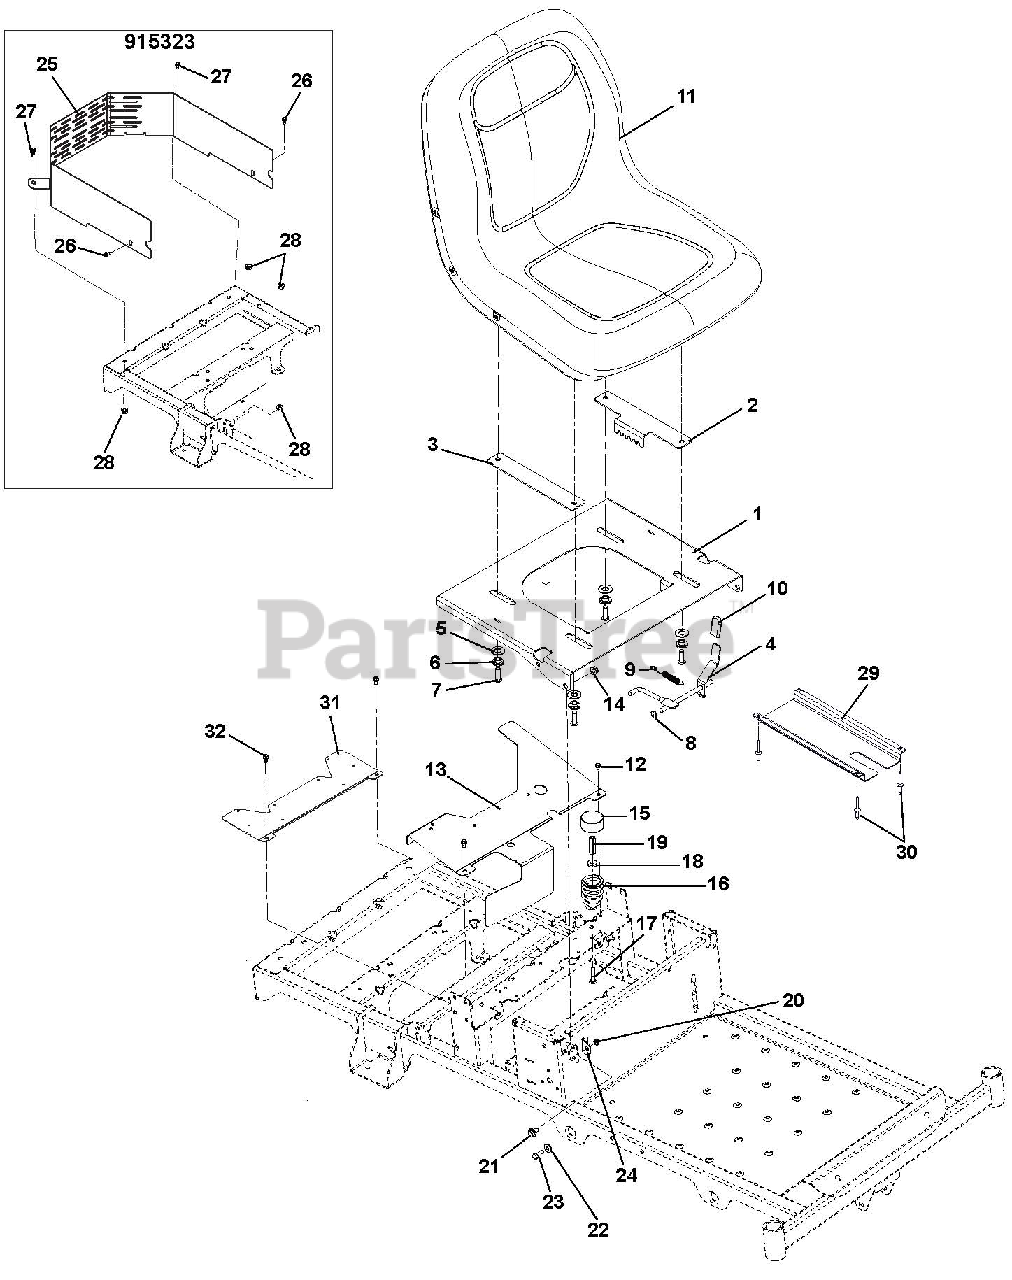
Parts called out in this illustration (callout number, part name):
1	PLATE, SEAT, ADJUSTABLE
2	PLATE, ADJUSTABLE SEAT TRACK
3	PLATE, ADJUSTABLE SEAT SLIDE
4	WLDMT, ADJUSTABLE SEAT LATCH
5	WSHR, FLT .505X1.00X.062 ZCC
6	BSHG-FLG .32X.500X.344X.880
7	BLT,SHCS-BTN .31-18X1.00 ZCC
8	NUT-PUSH .312
9	SG-TENS .043X.44X3.31 WLD 5.8
10	GRIP, SEAT LEVER, GREY
11	SEAT, MILSCO XB180 GRAY
12	@SCR-TAP .25-20X.50 HWH TR YWZ
13	COVER, ZOOM CE FAN
14	@NUT-LK-TOP-FLG .38-16 YWZC
15	HUB CAP
16	SPRING, SEAT
17	BLT,RHSN .31-18X1.50 G5 ZCC
18	WSHR, FLT .328X.870X.179 ZCC
19	NUT, COUPLING .31-18X1.75 ZCC
20	@NUT-LK-NYL-FLG .31-18 YWZC
21	BOLT-SHLDR .375-16X.150
22	BSHG-FLG .32X.500X.344X.880
23	@BLT-HEX .31-18X1.00 GR5 YWZC
24	BRKT, SEAT STOP
25	SHIELD, ZOOM REAR ENGINE
26	@BLT-HEX .38-16X.75 GR5 YWZC
27	@BLT-HEX .38-16X1.00 GR5 YWZC
28	NUT-LK-CTR-FLG .375-16 GF ZCC
29	GUARD, SEAT SWITCH
30	RIVET, #66 STEEL POP PD BLACK
31	KIT, FAN GUARD W/DECAL
32	SCR-TAP .25-20X.50 HWH ZCC
